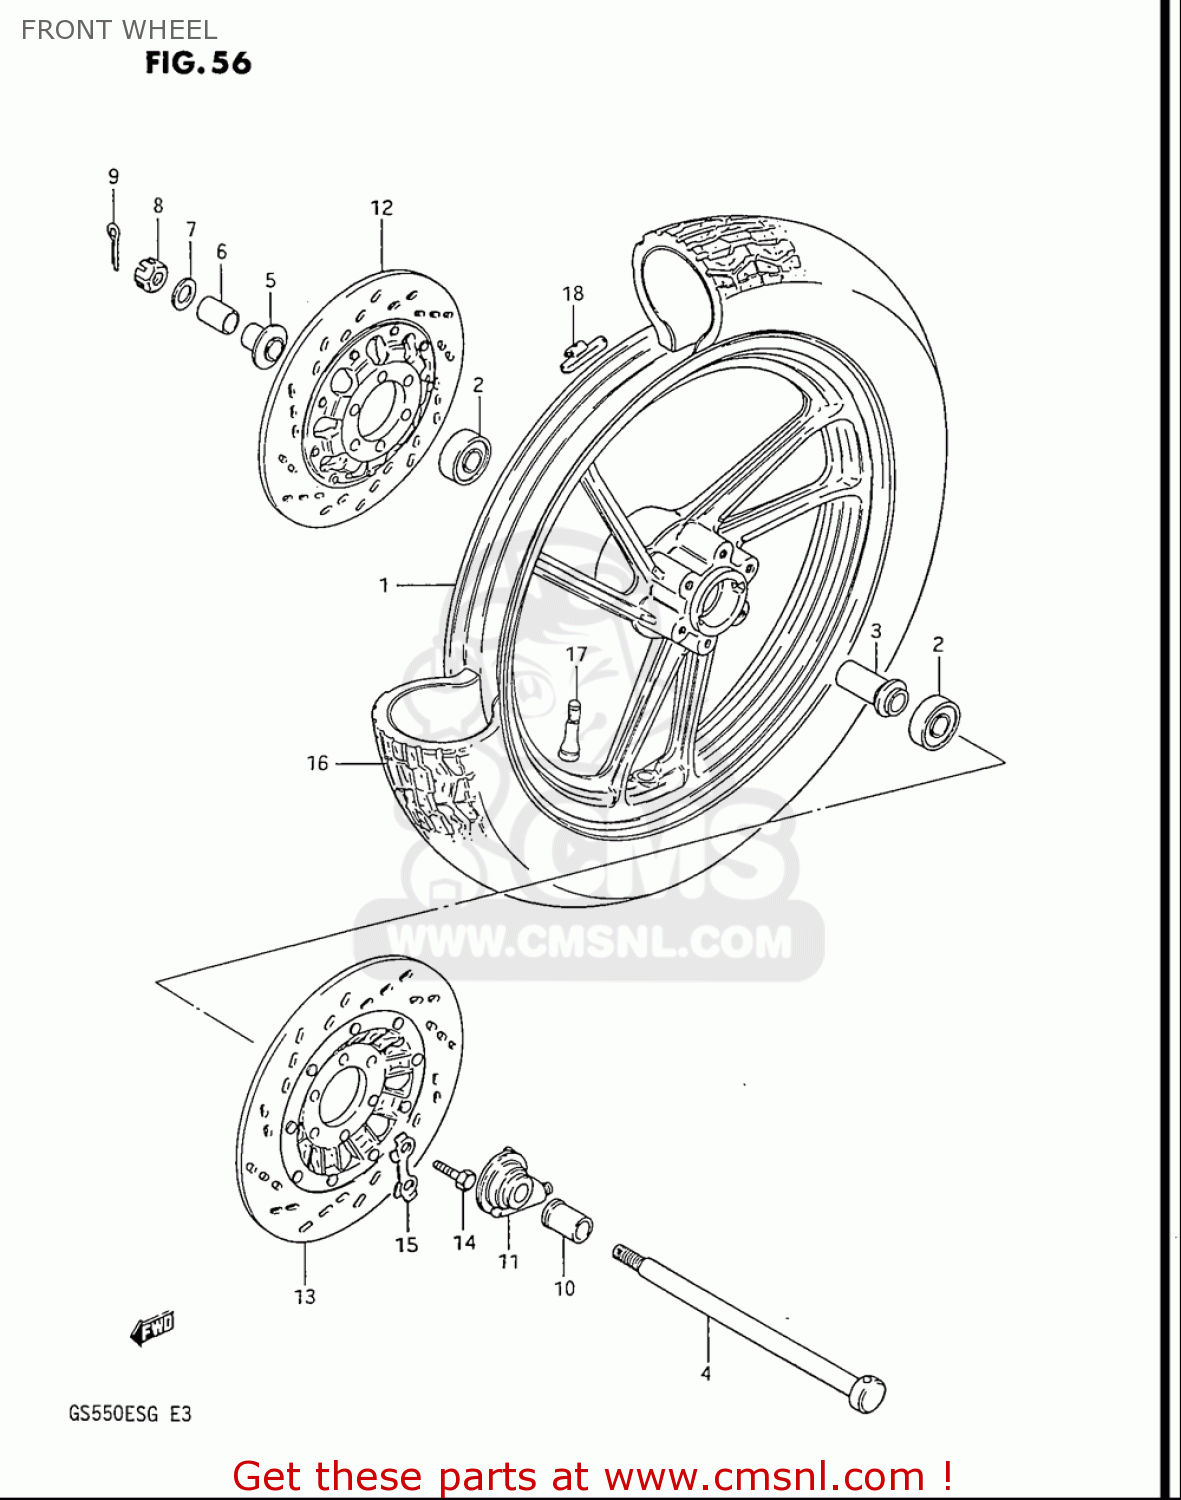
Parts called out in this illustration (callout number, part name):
1	WHEEL,FRONT (MT2.15X16)
3	SPACER,FR HUB BEARING
4	AXLE,FR
5	SPACER,FR AXLE,R
6	SPACER,FR AXLE,R
7	WASHER
8	NUT 12MM
9	PIN
10	SPACER,FR AXLE,L
11	BOX ASSY,SPEEDOMETER GEAR
14	BOLT(8X30)
15	WASHER
17	VALVE,TIRE TR413 BS
18	BALANCER,WHEEL(20G)
